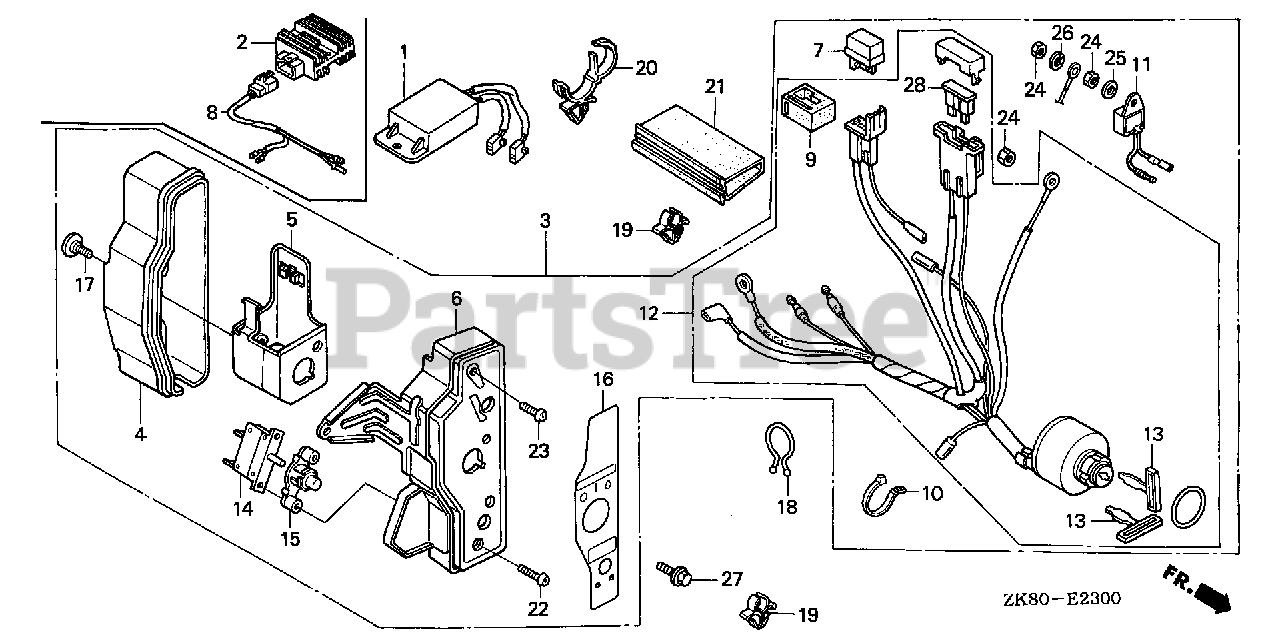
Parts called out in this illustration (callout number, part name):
1	RECTIFIER, REGULATOR
3	BOX ASSY., CONTROL *R280* (INTERNAL) (POWER RED)
3	BOX ASSY., CONTROL *R280* (EXTERNAL) (POWER RED)
4	CASE, CONTROL
5	BRACKET, CASE MOUNTING
6	PANEL, CONTROL *R280* (POWER RED)
7	RECTIFIER ASSY., SILICON (SHINDENGEN)
9	SUSPENSION, CONNECTOR
10	BAND
12	SWITCH ASSY., COMBINATION
13	KEY
14	PROTECTOR, CIRCUIT (1.0A)
15	LENS ASSY., PROTECTOR
16	PANEL, CONTROL BOX (INTERNAL)
16	MARK, CONTROL BOX (EXP)
17	SCREW, SPECIAL (6X12)
18	CLIP, PURSE LOCK
19	CLIP, CORD
20	STRAP, WIRE HARNESS (25MM) (BLACK)
21	TUBE, FASTENER (30MM)
22	SCREW, PAN (3X12)
23	SCREW, PAN (4X12)
24	NUT, HEX. (4MM)
27	BOLT, FLANGE (6X28) (CT200)
27	BOLT, FLANGE (6X10)
28	FUSE, BLADE (5A)
